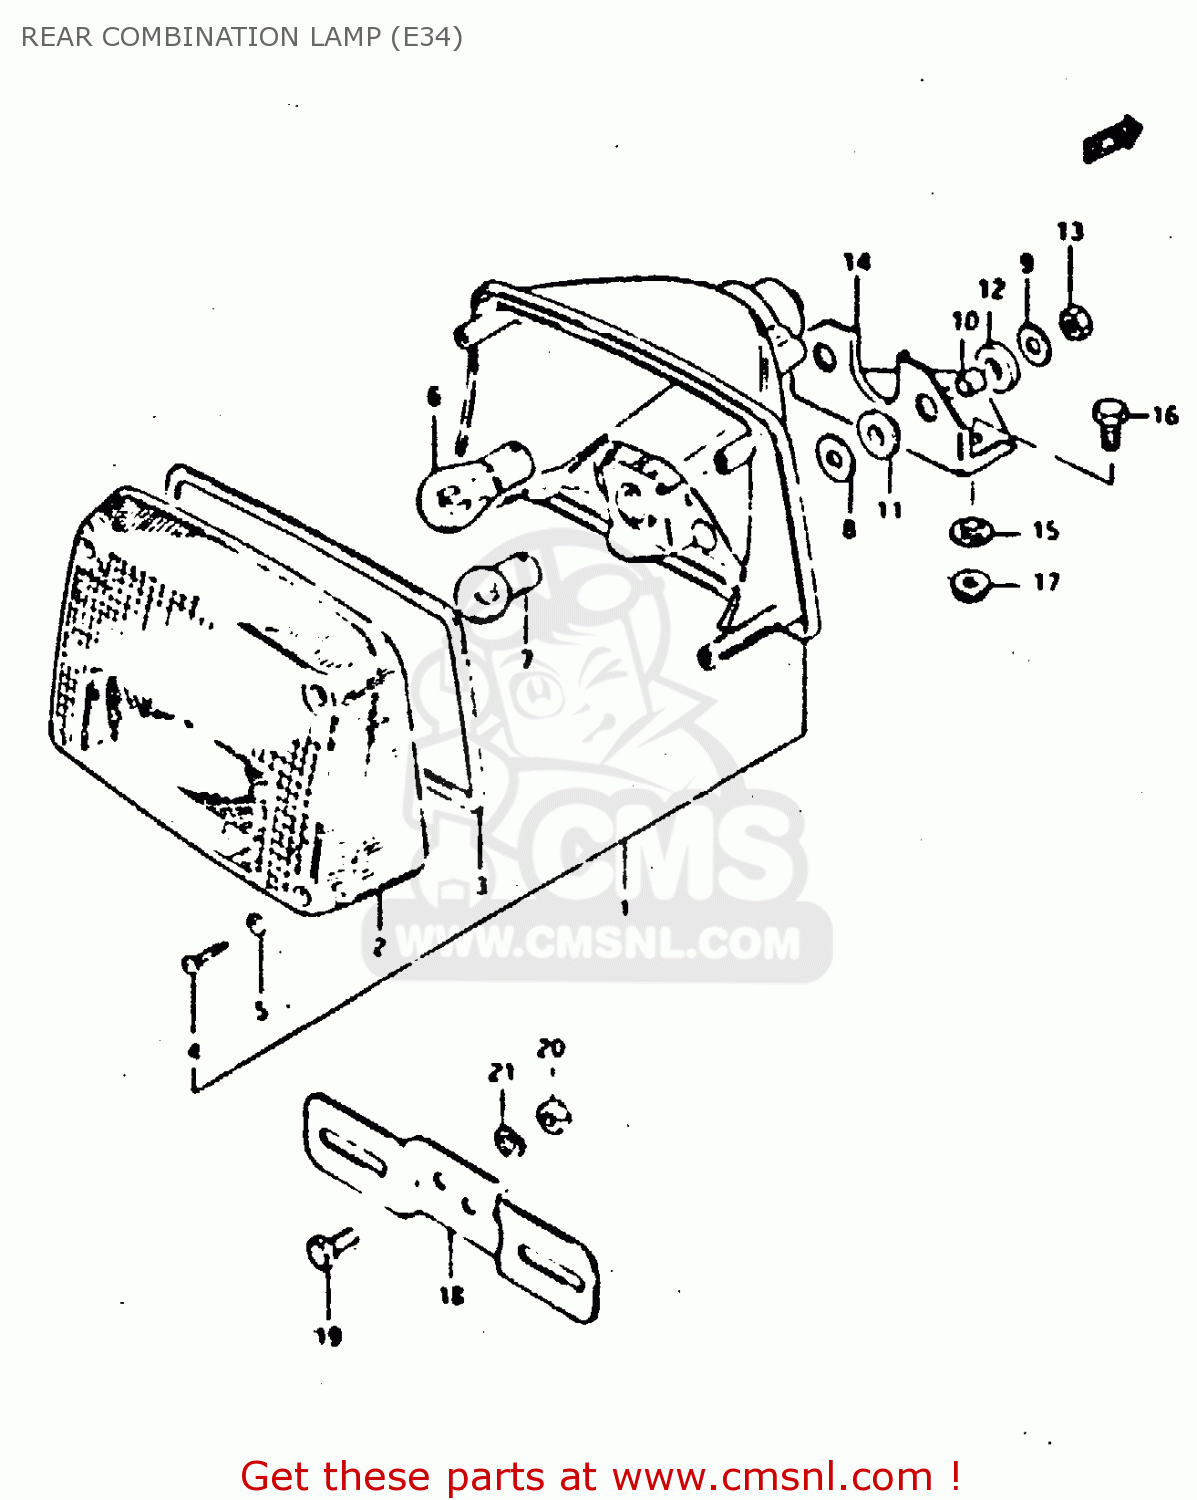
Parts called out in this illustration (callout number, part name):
1	LAMP, REAR COMBINATION
2	LENS
3	GASKET (NAS)
4	SCREW,REAR COMBINATION LAMP
5	GASKET (NAS)
6	BULB(12V21/5W)
7	BULB
8	WASHER
9	WASHER(6,5X22X1.6)
10	SPACER(6.1X9X7.5)
11	CUSHION
12	CUSHION
13	NUT 6MM
14	BRACKET,RR COMBINATION LAMP
15	WASHER
16	BOLT, UPPER
17	NUT 6MM
18	BRACKET, LICENSE PLATE
19	BOLT,REAR
20	NUT
21	LOCK WASHER
